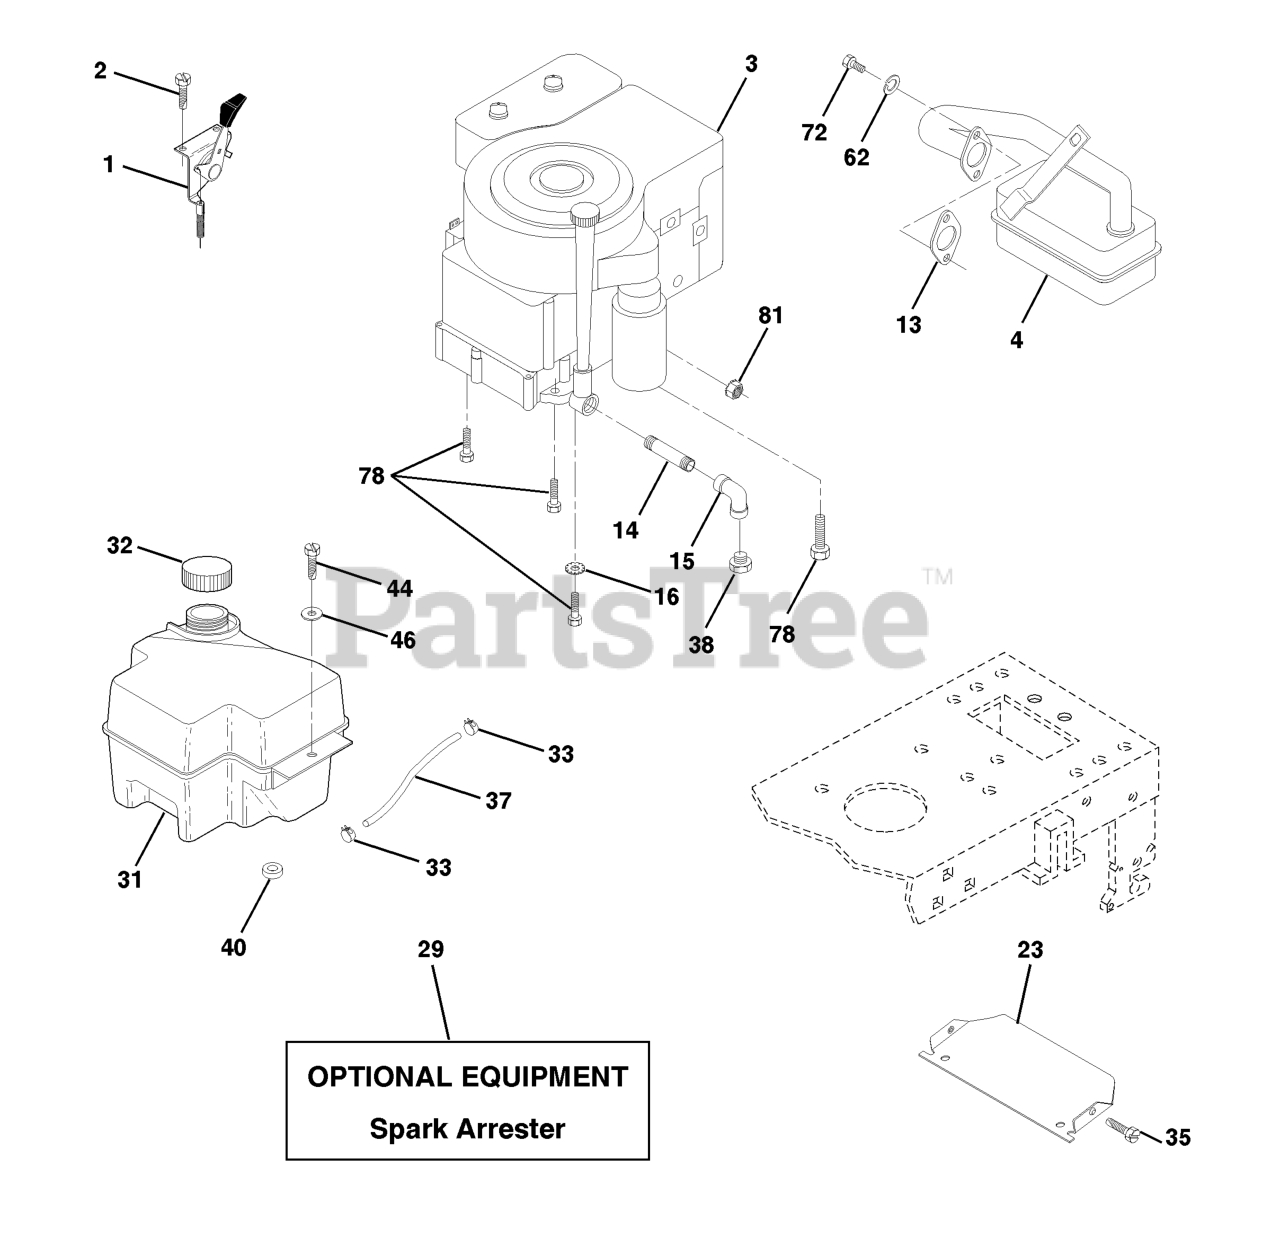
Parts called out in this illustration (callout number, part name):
1	CHOKE CONTROL
2	SCREW LT
4	MUFFLER.SINGLE.B&S.10-12HP
13	GASKET.ENG.1.313 ID.TIN PLATED
14	Nipple Pipe 3/8 Npt X 3"
15	ELBOW
16	LOCKWASHER
23	SHIELD HEAT
29	KIT.SPARK ARRESTOR 794945 B&S
31	FUEL TANK
32	FUEL CAP
33	HOSE CLAMP
35	SCREW.THDROL.5/16-18X3/4.TTY
37	LINE.FUEL.20
38	Plug Oil Drain
40	BUSHING.SNAP.NYL.BLK.
44	SCREW HEX CRT
46	WASHER
62	WASHER.LOCK.HVY.HLCL.SPR.5/16
72	SCREW
78	SCREW
81	NUT FLANGE 1/4-20 STARTER NUT
